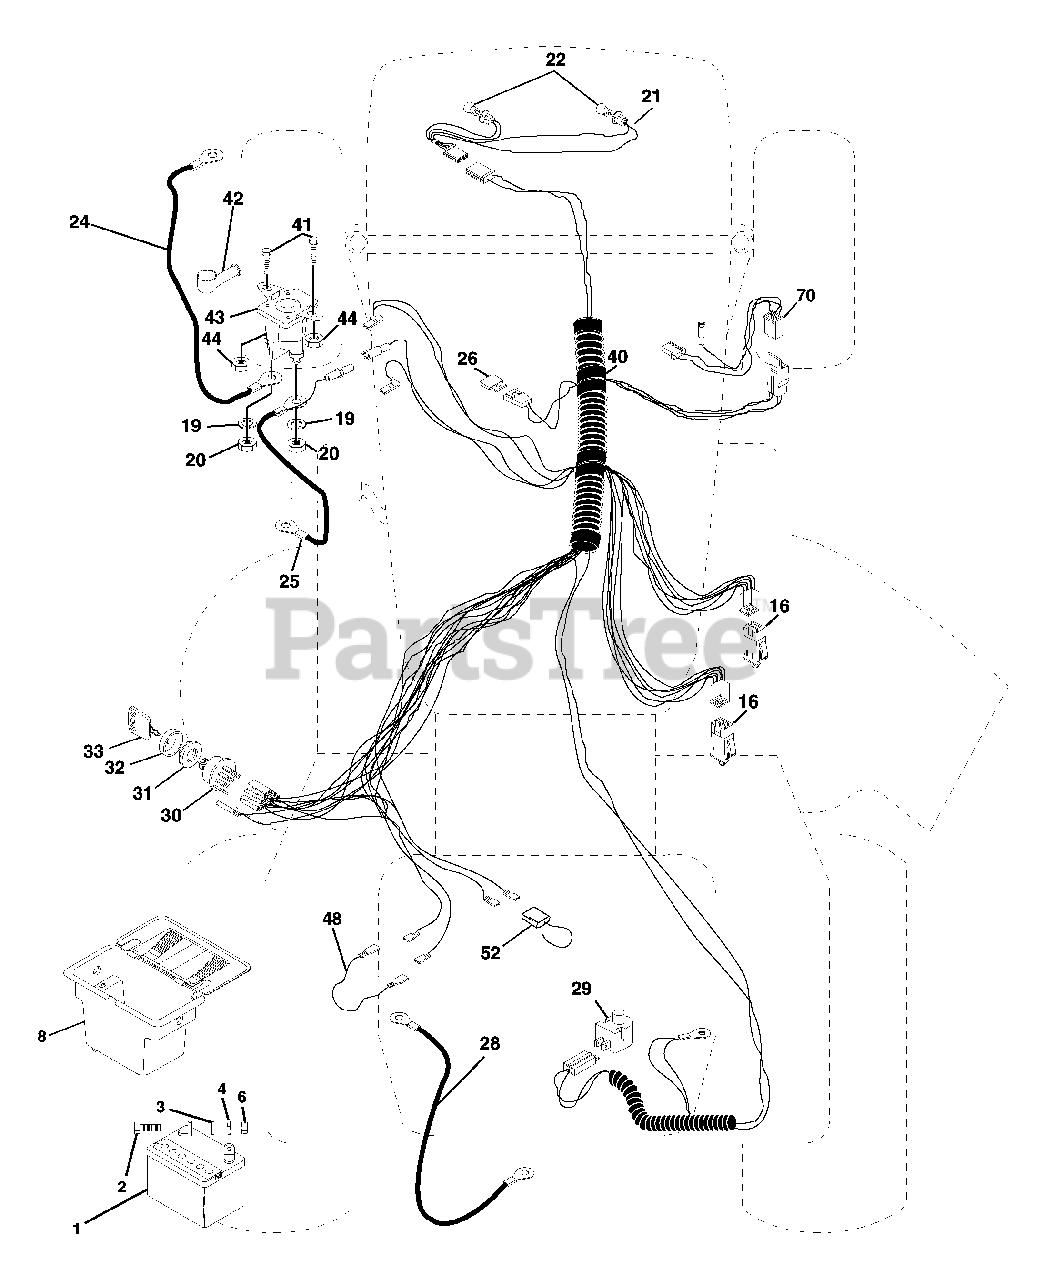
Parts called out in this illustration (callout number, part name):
1	Battery 12 Volt 25 Amp
2	Bolt Hex Hd 1/4-20unc X 3/4
3	Washer 9/32 X 5/8 X 16 Ga
4	Washer Lock Hvy Helical 1/4
6	Nut Fin Hex 1/4-20 Unc
8	Case Battery Mech Heinge
16	Switch Interlock Push-In
19	Washer Lock 1/4
20	Nut Jam Hex 1/4-20 Unc
21	Harness Asm Light W/4152j
22	Bulb Light #1156
24	Cable Battery 6 Ga 11" red
25	Cable Battery
26	Fuse 30 AMP Auto Green
28	Cable Ground 6 Ga 12" black
29	Switch Plunger Nc Gray
30	Switch Ign 4
31	Nut Ignition
32	Cover Sw Ignition
40	Harness Ign
41	Bolt Blk Fin Hex 1/4-20
42	Cover Terminal Red
43	Solenoid
44	Nut Keps Blk Hex 1/4-20 Unc
48	Adapter Ammeter
52	Protection Wire Loop
70	Harness Eng Briggs/Tec Dual
